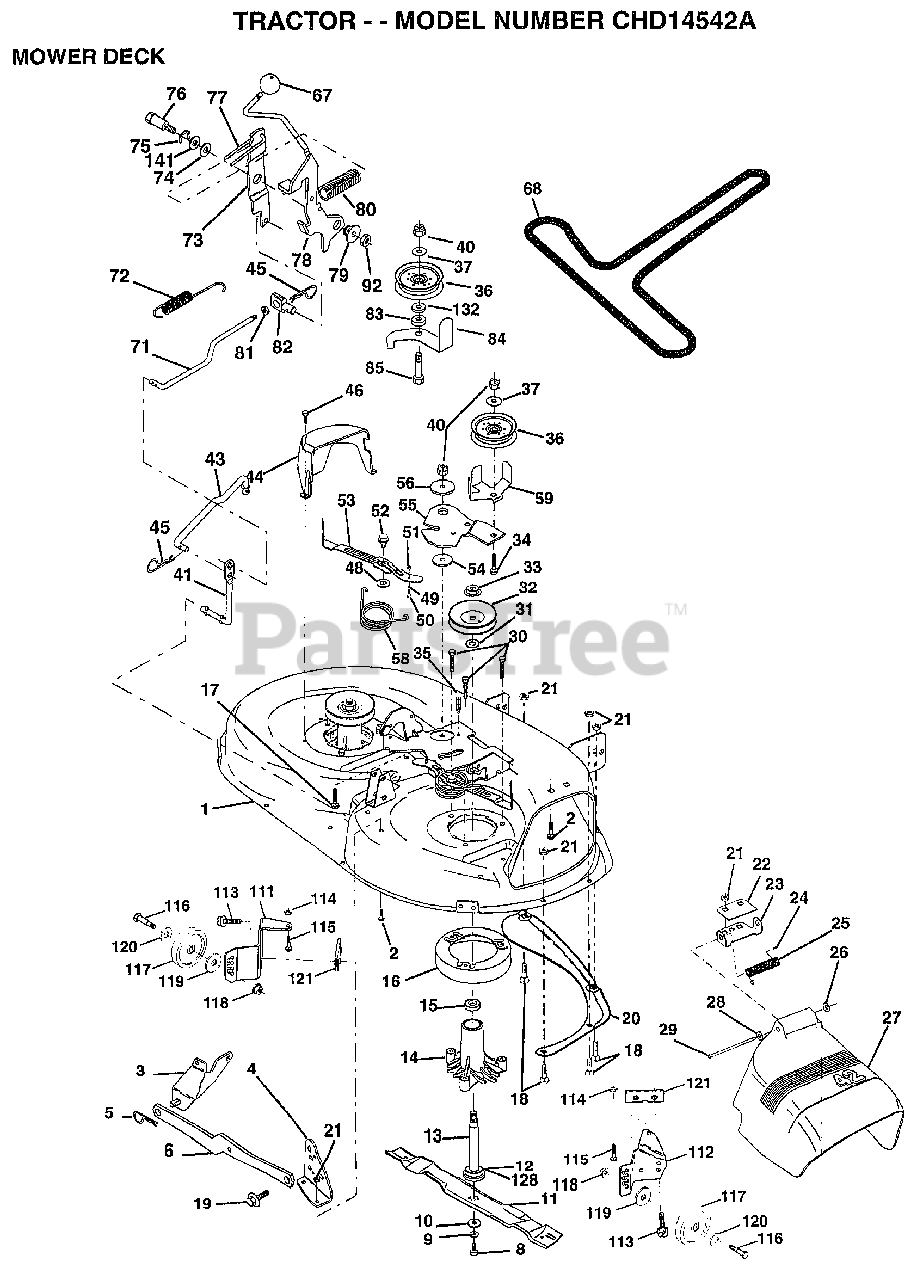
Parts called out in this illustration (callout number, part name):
1	"HOUSING ASSY.42"""
2	BOLT
3	BRKT ASM SWAY BAR
4	BRKT DECK SW BAR
8	BLADE BOLT
10	WASHER.HARD.BLADE
11	"BLADE.42"" HIPERF"
12	BEARING.BALL
14	HSG ASM MANDREL
15	BEARING
16	STRIPPER RND MWR
17	BOLT RDHD 3/8-16
18	BOLT
19	BOLT SHD 5/16-18
20	BAFFLE VORTEX 42
22	STIFFENER BRKT
23	DEFLECTOR BRKT
24	CAP-SLEEVE LT
25	SPRING TORSION
26	NUT PUSH M
27	DEFLECTOR.SHIELD
28	WASHER
29	HINGE ROD
30	"SCREW-THD ROLL,WA"
31	WASHER
32	PULLEY.MANDREL.42
34	BOLT
35	XMAS TREE FASTNER
36	FLAT IDLER PULLEY
37	WASHER
41	PIVOT ROD
43	ROD CLUTCH W/NIBS
44	GUARD MAND LH BLK
45	RETAINER M
46	SCREW.1/4-20X5/8
48	HARD SMALL WASHER
49	ROLLER ASM-CAM
50	SHOULDER BOLT
51	LOCKNUT
52	BOLT.SHLD.5/16-18
53	BRAKE PAD ARM ASM
54	HARDENED WASHER
55	ARM-IDLER
56	SPACER RETAINER
58	SPRING TORSN BRAK
59	GUARD IDLER TUV
67	KNOB.RD.7/16-14
68	BELT.V.T-PATH
71	ROD CLUTCH 38/42
72	RETURN SPRING
73	CLUTCH ARM SECOND
74	WASHER
75	RING
76	SHOULDER BOLT
77	SPRING KEEPER
78	LEVER.ASM.CLUTCH
79	BUSHING
80	SPRING.CLUTCH.MWR
81	NUT
82	TRUNION ADJ
83	WASHER
84	"KEEPER-BELT,FIXED"
85	BOLT
92	NUT
111	BRACKET.GWHL.LH.
112	BRACKET.GWHL.RH.
113	SCREW
116	BOLT M
117	WHEEL.GAGE.BLK.PL
118	LOCKNUT
119	WASHER
120	WASHER
121	BRACKET.EXTRD.GWL
128	WASHER.FELT.
132	WASHER GT
141	WASHER .T
